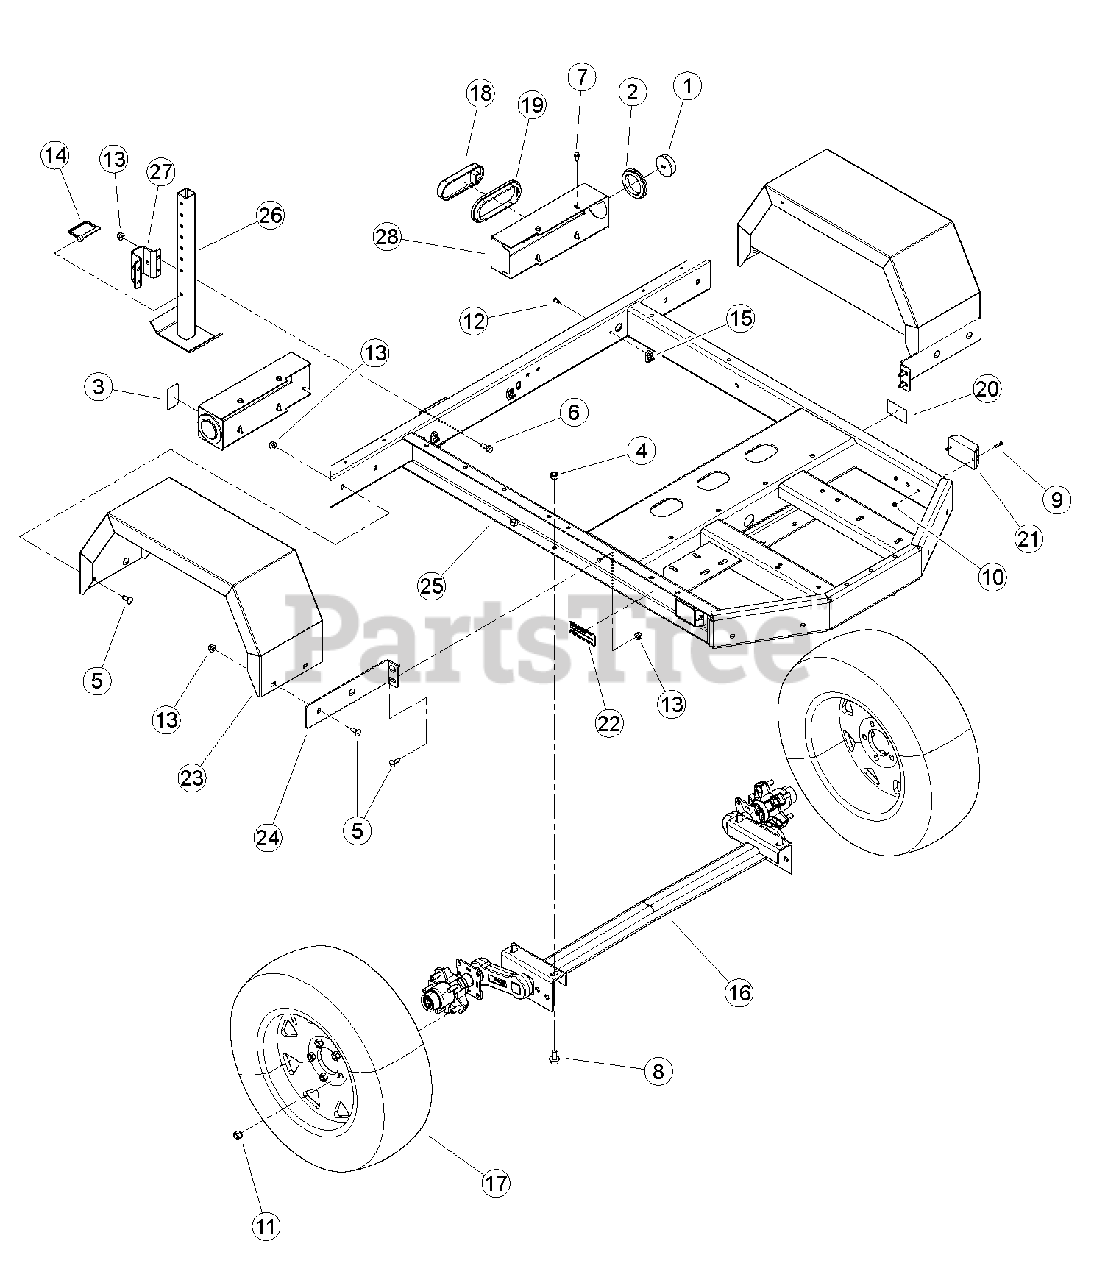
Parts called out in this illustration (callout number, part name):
1	LIGHT, RED CLEARANCE
2	GROMMET, CLEARANCE LIGHT
3	REFLECTOR, WIDE ANGLE RED
4	NUT, 1/2" CENTERLOCK GRB ZP
5	BOLT, 3/8 X 1" GR5 CRG NC ZP
6	BOLT, 3/8 X 1 FLANGE NC
7	SCREW, 11/32 X 7/8 HWH AB THREAD ZP
8	BOLT, 1/2-13 1.00 GR5 FLANGE NC
9	SCREW, MCH 10-24 X 1" RND HD PHL ZP
10	NUT, 10/24 NYLOCK TYPE NM ZP
11	NUT, 1/2-20 WHEEL
12	RIVET, AL BLIND 1/4 X 3/4 DOME HEAD
13	NUT, 3/8-16 NYLOCK FLANGE
14	PIN, 3/8 X 2-3/4" SNAP
15	CLAMP, CABLE MOUNT
16	AXLE, TORSION 1800
17	ASSEMBLY, TIRE AND WHEEL 14 IN
18	TAIL LIGHT, OVAL LED
19	GROMMET, OVAL TAIL LIGHT
20	DECAL, P205/75R14 LOAD RATING
21	LIGHT, AMBER MARKER
22	DECAL, EPA EVAP
23	WELDMENT, 6" CHIPPER FENDER
24	BRACKET, 6" FENDER
25	WELDMENT, 6" CHIPPER TRAILER
26	WELDMENT, REAR STABILIZER
27	GUIDE, TRAILER SUPPORT
28	BRACKET, TAILLIGHT
